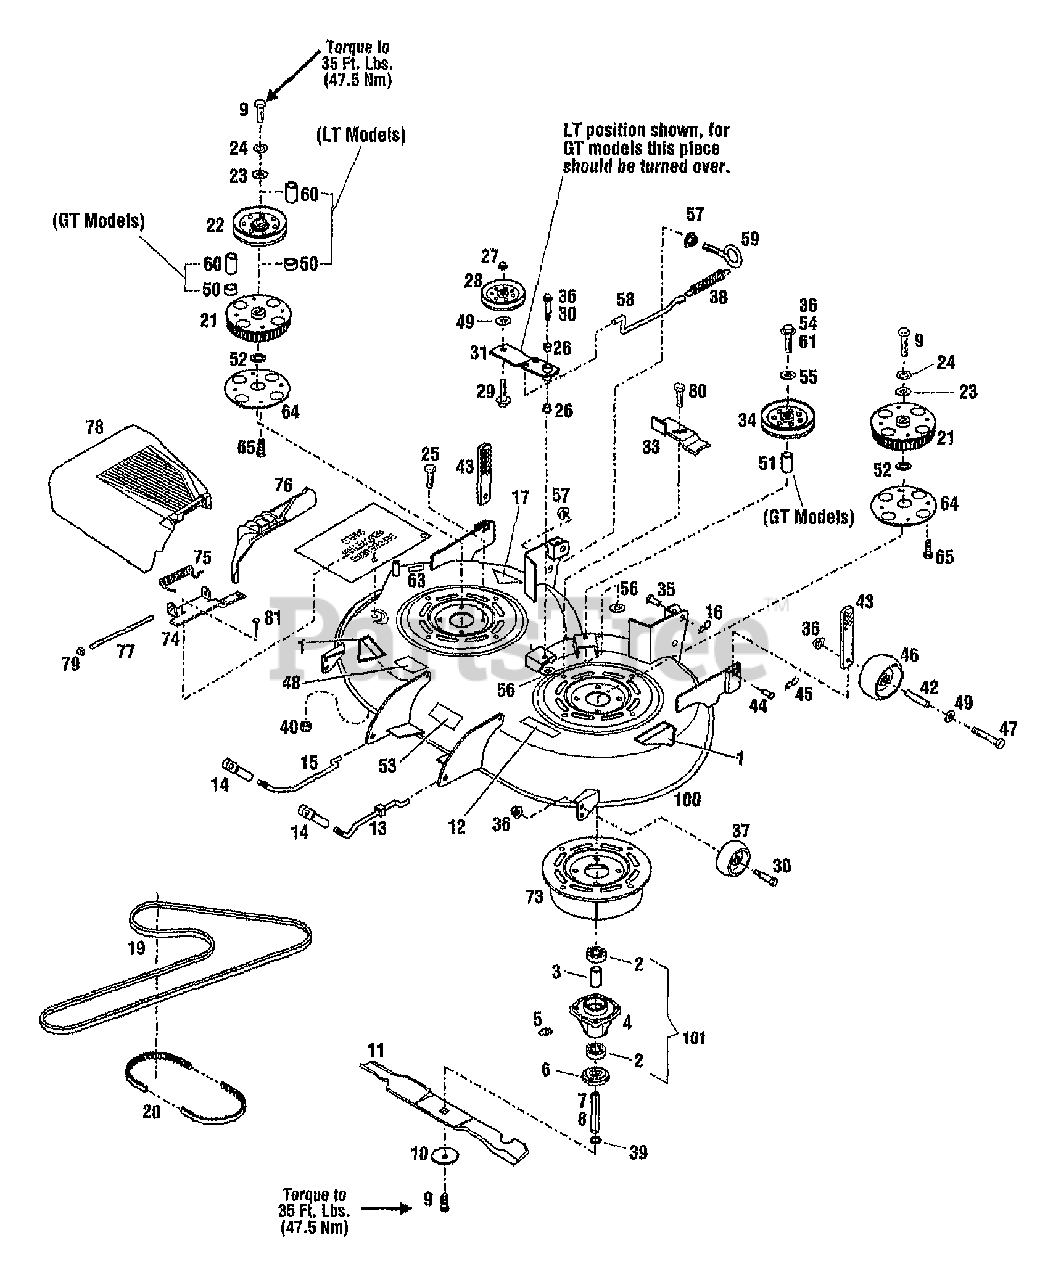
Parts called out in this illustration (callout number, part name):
1	DECAL-OPEI CAUTION
2	BEARING-BALL
4	HOUSING-SPINDLE
5	FITTING-GREASE 90 DEGREE
6	SPACER-BLADE
7	SHAFT-SPINDLE MED. H/T
8	SHAFT-LONG SPINDLE (RH)
9	SCR-HH 1/2-14X1.00
10	WASHER-BELLEVILLE
11	BLADE-38" MULCHING
12	NAME PLATE
13	ROD-LIFT FRONT LH
15	ROD-LIFT FRONT RH
16	PIN-HITCH .125X2.56 ZP
17	DECAL-OPEI
20	BELT-DRIVE 38"
21	SPROCKET-56T GRIVORY
22	ASSM-SHEAVE DRIVE
23	WASHER-1.37X.453X.179 ZP
24	WASHER-LK .438 ZP
25	SCR-HFLK 5/16-18X1.00
26	BUSHING-.5X.5 NYLON FLNG
27	NUT-HFLK 3/8-16 ZP
28	PULLEY-IDLER
29	SCR-HH 3/8-16X1.75 G5 ZP
30	SCR-SHLDR 3/8-16
31	ASSM-IDLER ARM
33	BRKT-BELT TENSIONER
35	PIN-CLEVIS .625X2.25
36	NUT-LOCK 3/8-16
37	WHEEL-GAGE
38	SPRING
39	RING-RETAINING EXT .694 ID
40	NUT-TOP/LK 5/16-18 ZP
42	SPACER-GAGE WHEEL
43	LEVER-GAGE WHEEL ADJUST
44	PIN-CLEVIS .375 X .937 ZP
45	CLIP-HAIRPIN .07 DIA
46	WHEEL-GAGE
47	SCR-HH 3/8-16X3.5 G5 ZP
48	DECAL-BELT DRIVE
49	WASHER-.986X.437X.083 ZP
50	SPACER-1.25X.76X.50
51	SPACER
52	HARDENED WASHER
53	DECAL-LIFT ROD
54	SCR-HH 3/8-16X3.0 G5 ZP
55	WASHER-LK .375 @ DEPL
56	SPACER-SPECIAL 1/4
57	NUT-HFLK 5/16-18 ZP
58	ROD-IDLER
59	BOLT-EYE SC
60	SPACER-1.25X.77X.88
61	SCR-HH 3/8-16X1.75 G5 ZP
63	DECAL-DANGER
64	PLATE-SPROCKET COVER
65	SCR 1/4-20.75 TRI-PLASK
73	PLATE-DOUBLER
74	BRKT-DISCHARGE CHUTE
75	SPRING-TORSION
76	ASSM-COVER
77	PIN-DEFLECTOR ZP
78	CHUTE-DISCHARGE
79	CAP-PUSH ON .312 DIA
80	SCR-HFLK 5/16-18X.625 STH
81	SCR-CARR 5/16-18X.75 G2 ZP
100	BASE-MOWER 38" W/DECALS
101	ASSM-MOWER SPINDLE
